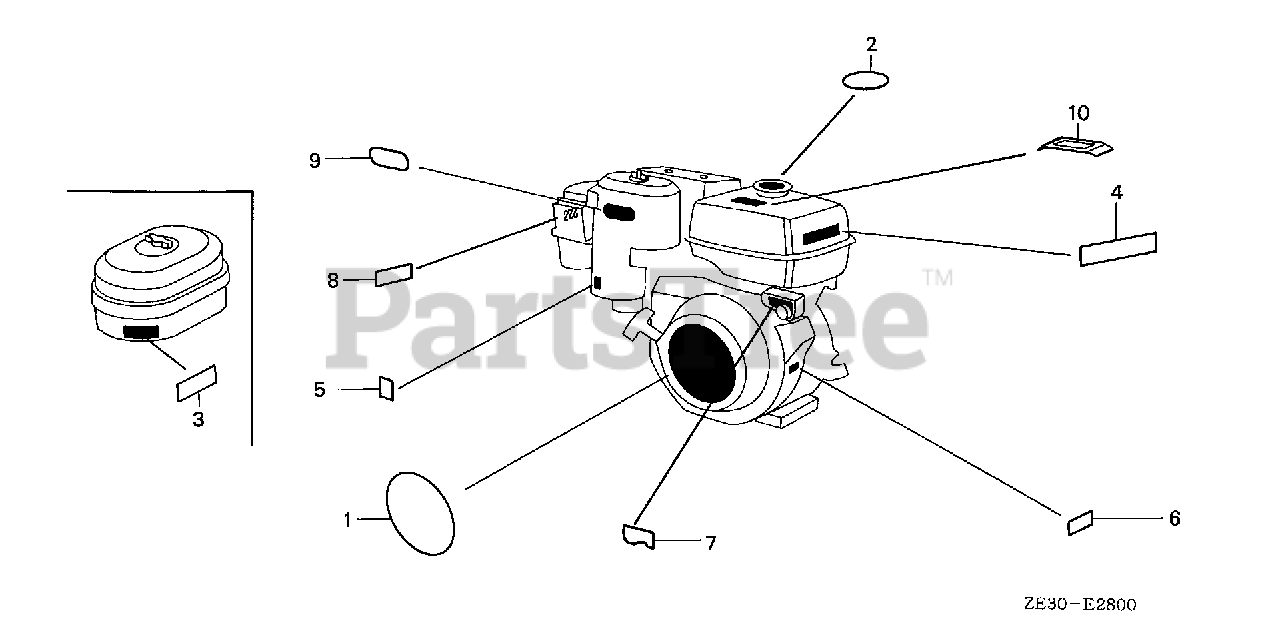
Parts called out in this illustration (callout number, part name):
1	EMBLEM (EXP-ALERT) (NOT AVAILABLE)
2	MARK, CAUTION
5	MARK, CHOKE (ORANGE)
7	MARK, OIL ALERT (EXTERNAL) (NOT AVAILABLE)
